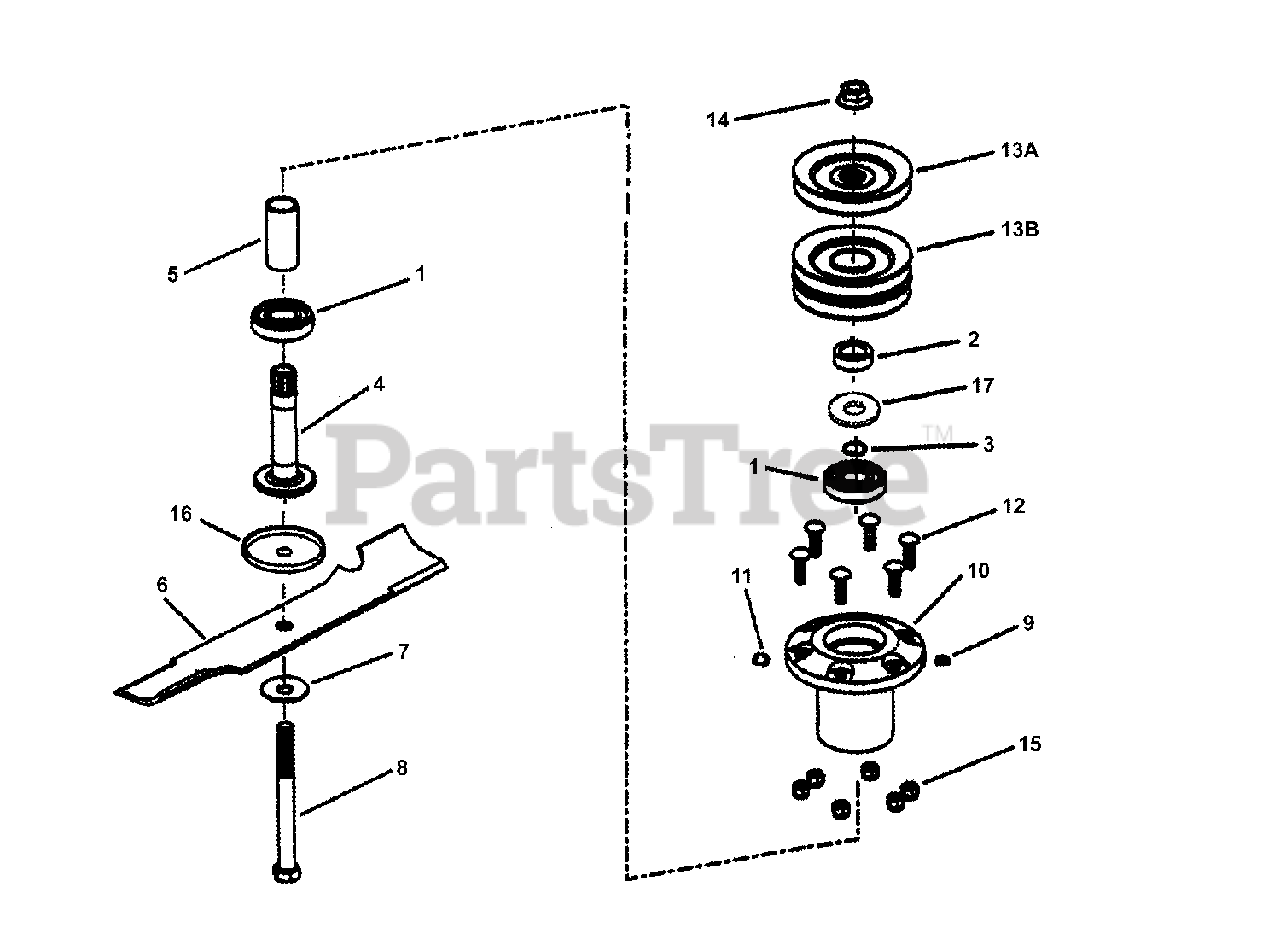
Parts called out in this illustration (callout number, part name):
1	BALL BEARING, Sealed
2	SPRING, Extension- Primary Idler
3	SNAP-RING, Spindle Shaft
4	SHAFT, Spindle
5	SPACER, Bearing
6	BLADE, 16-1/2"
7	WASHER, Belleville
8	BOLT, 5/8-18 x 6-5/8" Hex Head, GR5
9	LUBE FITTING, 1/4-28 Thread Forming
10	HOUSING, Cutter
11	VENT, Spindle
12	BOLT, 3/8-16 x 1-1/4" Rib Necked
13A	PULLEY, Spindle (48" Deck L.H. & R. H.)
13B	PULLEY, Spindle (48" Deck Drive)
14	NUT, 5/8-18 Hex Flange Lock, GR5
15	NUT, 3/8-16-3B Hex Nyloc
16	CUP, Spindle Cover
17	SEAL, Nylos
